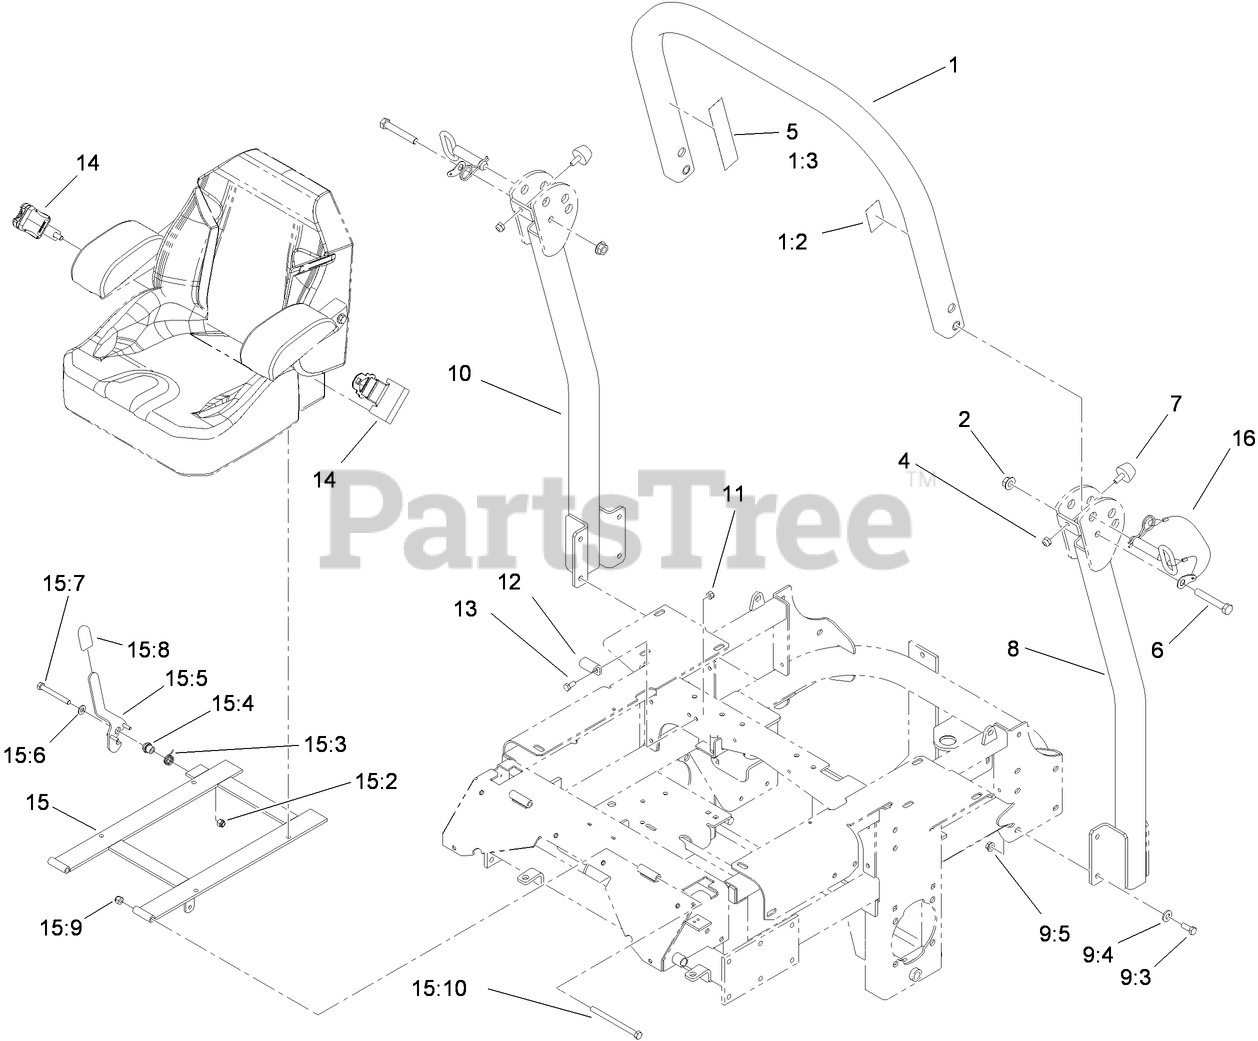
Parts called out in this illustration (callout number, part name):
1	Upper Tube ASM
1:2	DECAL-ROPS
1:3	DECAL-WARNING, FOLDING ROPS
2	NUT-HF
4	NUT-LOCK, NI
5	DECAL-WARNING
6	SCREW-HH
7	BUMPER-RUBBER
8	TUBE-SUPPORT, LH
9	BAG-BOLT, ROPS
9:3	SCREW-HH
9:4	WASHER-BELLEVILLE
9:5	NUT-HHF, WHIZ
10	TUBE-SUPPORT, RH
11	NUT-LOCK, NI
12	Catch-Latch, Seat
13	SCREW-HH
14	SEAT BELT KIT
15	SEATFRAME ASM
15:2	NUT-LOCK, NI
15:3	SPRING-TORSION
15:4	BUSHING-LATCH, SEAT
15:5	LATCH ASM
15:6	WASHER-FLAT
15:7	SCREW-HH
15:8	GRIP-LEVER
15:9	NUT-LOCK, NI
15:10	SCREW-HH
16	PIN-FOLD, ROPS
